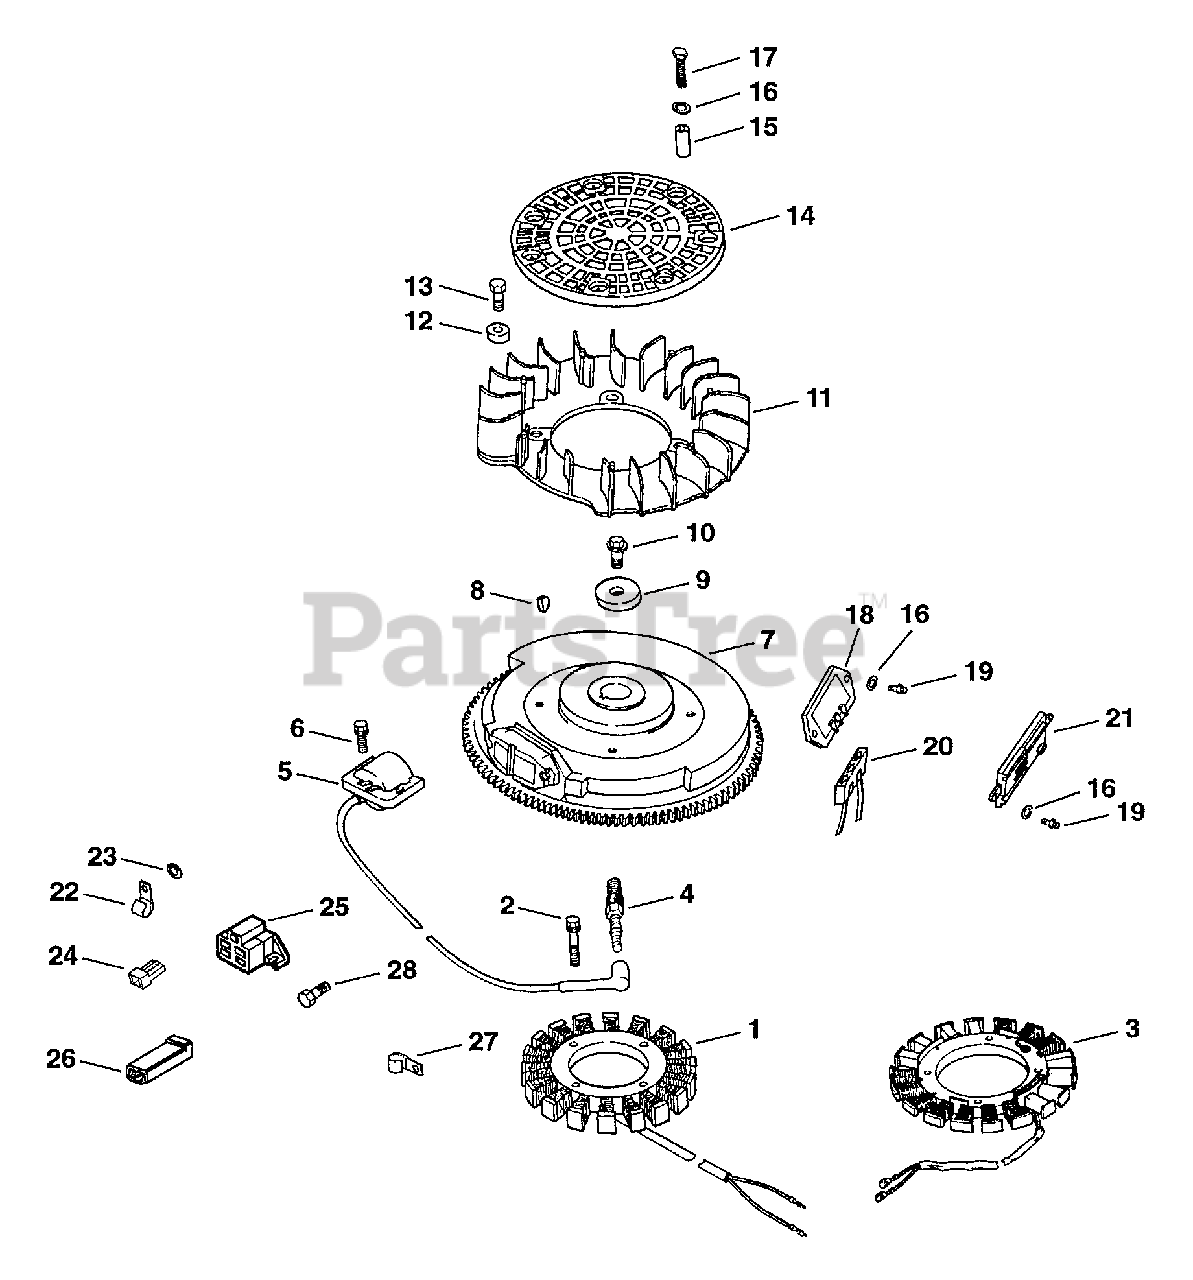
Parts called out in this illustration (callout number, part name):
1	KIT - USE 54 755 09
2	SCREW - USE M-548025
4	PLUG, SPARK (STD)
5	MODULE, IGNITION-USE 24 584 45-S
6	Screw, hex. flange M5x0.8x20
7	FLYWHEEL, PAINTED-USE 24 025 55-S
8	KEY, 3/16" X 5/8"
9	WASHER, FLAT 13/32"
10	SCREW, FLG M10X1.5X45 - (#25086361S)
12	BOLT - USE 25 086 47
13	SCREW - USE M-639016
14	KIT - USE 54 755 15
15	SPACER - DISCONTINUED
16	WASHER, FLAT 3/16"
17	Screw, hex. cap M4x0.7x25
19	SCREW, PHL HD #11-16X7/8"
20	CONNECTOR, BODY (KM)-USE 25 155 41-S
23	WASHER, FLAT 1/4" (O.D. 1/2")
27	CLIP, CABLE
2417612-S	HARNESS, WIRING
2451804	LEAD - USE 25 518 34
